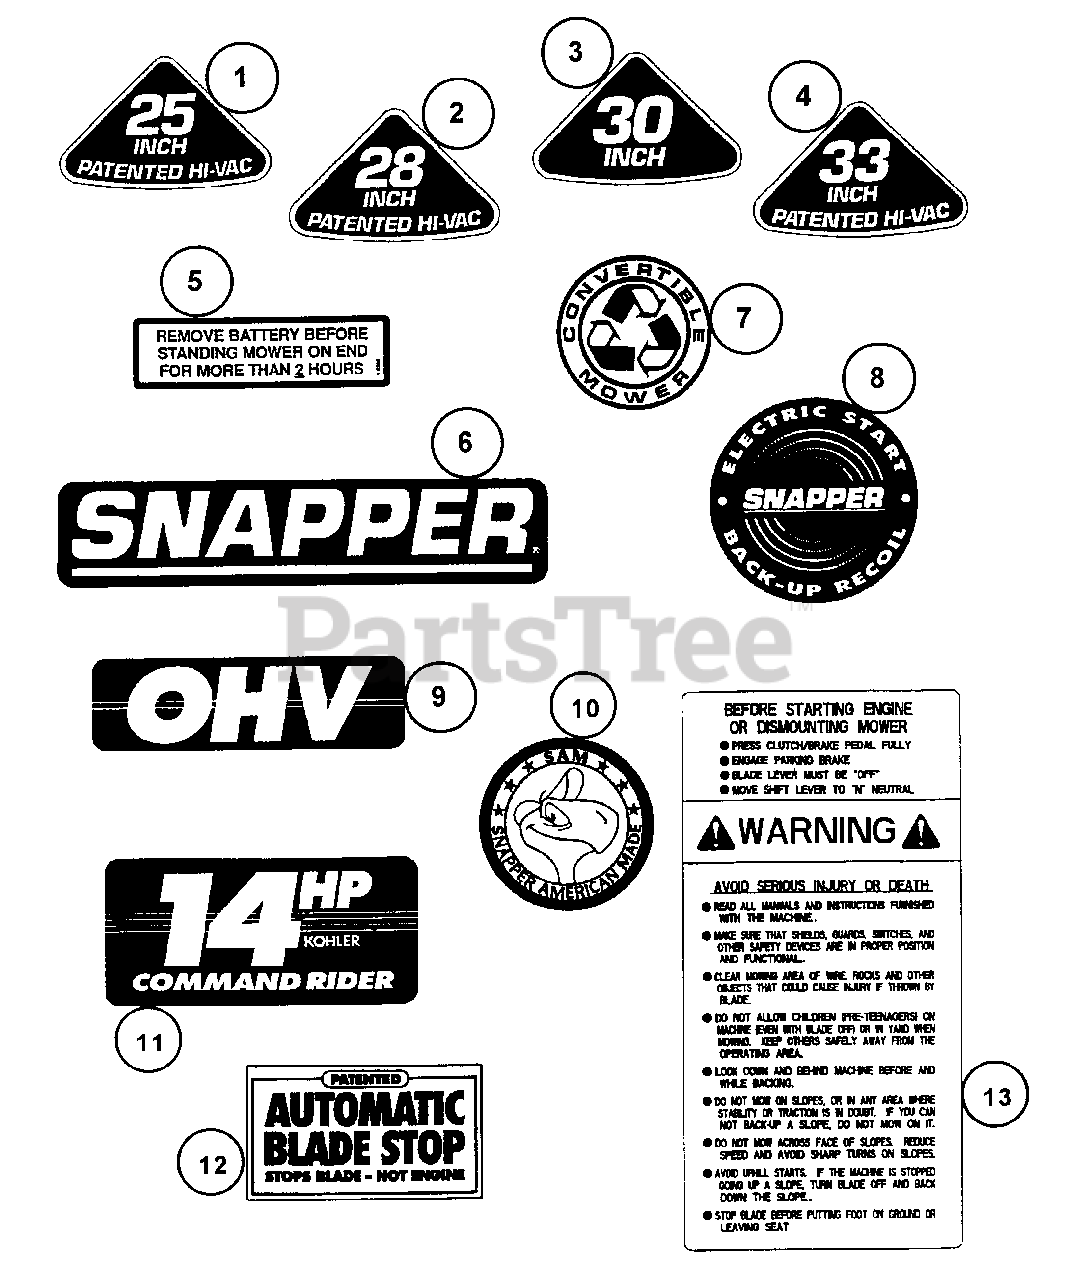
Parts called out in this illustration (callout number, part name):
1	DECAL, 25 Inch
2	DECAL, 28 Inch
3	DECAL, 30 Inch
4	DECAL, 33 Inch
5	DECAL, Battery
6	SNAPPER, (Molded Logo)
7	LOGO, Convertible (Silver)
8	DECAL, Back-Up Recoil
9	DECAL, OHV
10	MEDALLION, Sam
11	DECAL, 14 HP
12	DECAL, Auto Blade Stop (Point of Purchase Decal)
13	DECAL, Safety Instruction Warning
